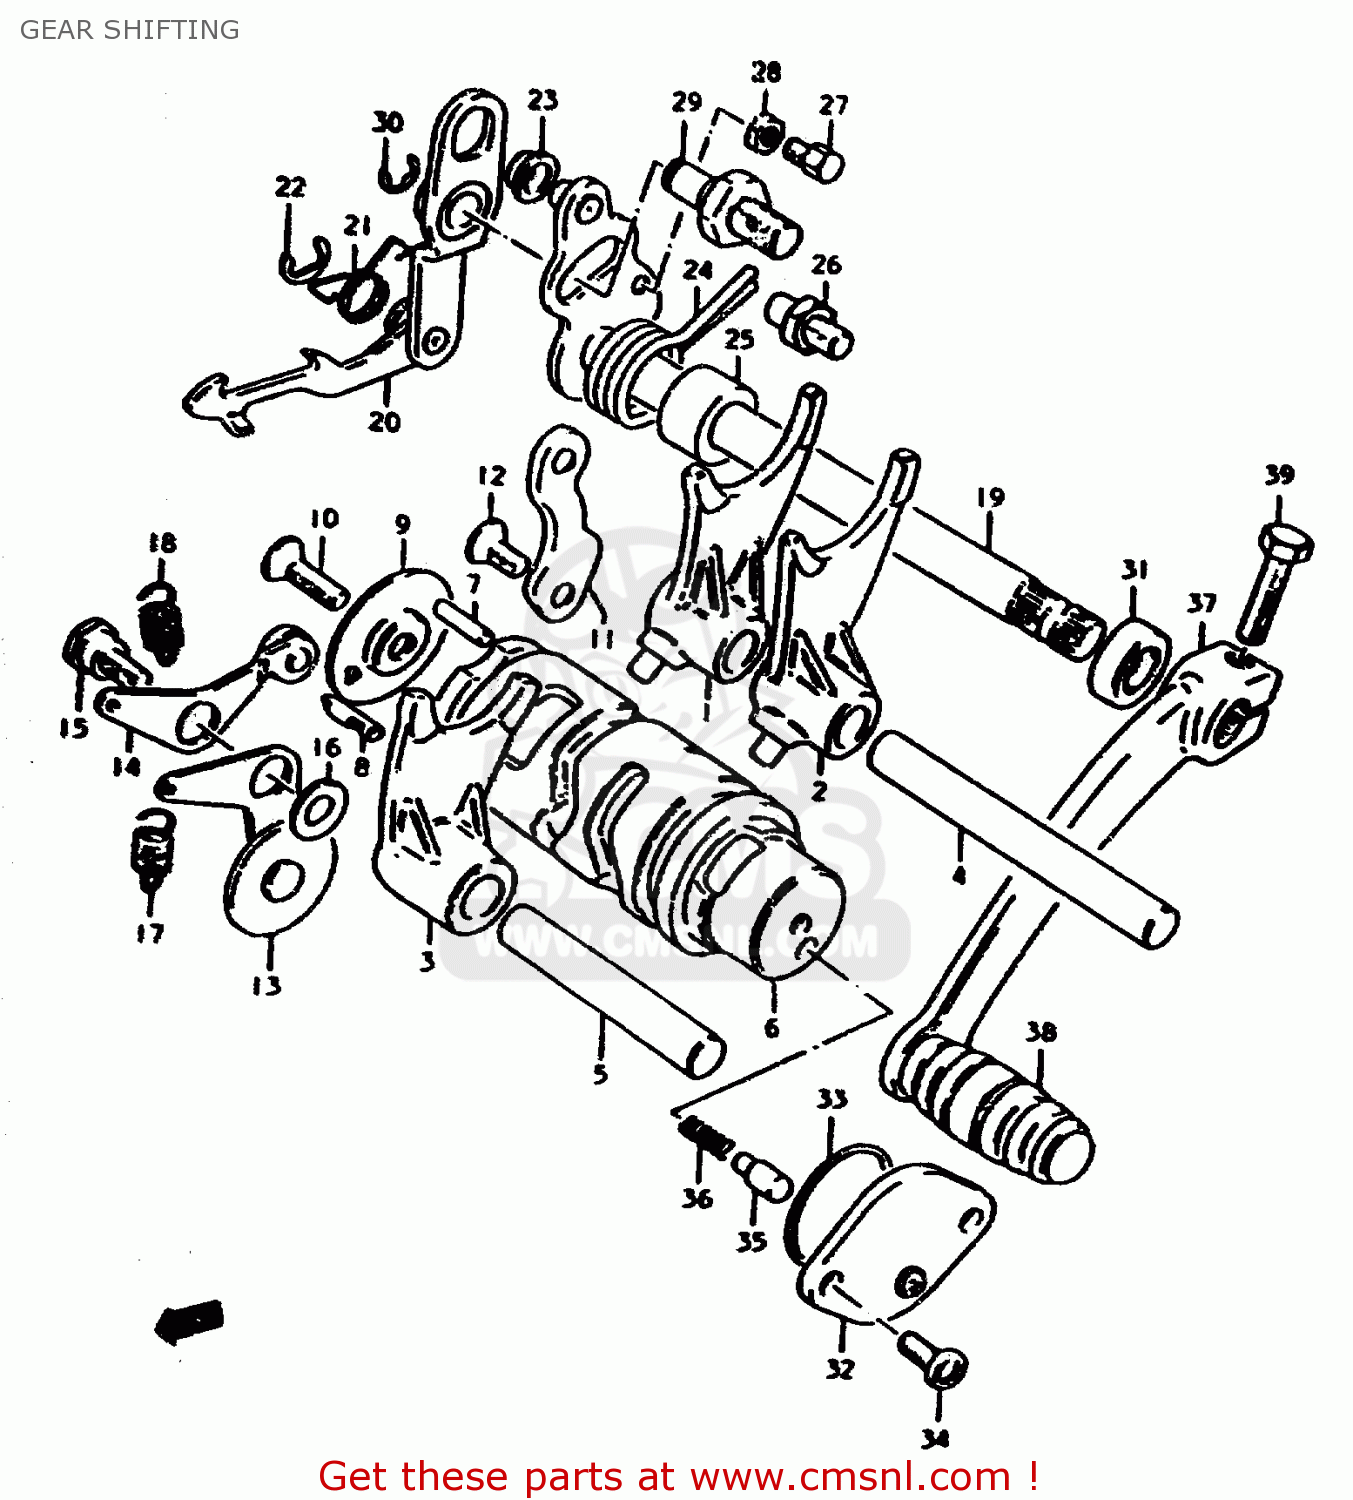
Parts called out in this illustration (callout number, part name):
1	FORK,GEAR SHIFT NO.1
2	FORK,GEAR SHIFT NO.2
3	FORK,GEAR SHIFT NO.2
4	SHAFT,GEAR SHIFT FORK
5	SHAFT,GEAR SHIFT FORK
6	CAM,GEAR SHIFT
7	PIN(4X15.8)
8	PIN
9	RETAINER,GEAR SHIFT CAM DR PIN
10	SCREW
11	GUIDE,GEAR SHIFT CAM
12	SCREW
13	STOPPER,GEAR SHIFT CAM
14	STOPPER,GEAR SHIFT CAM NEUTRAL
15	BOLT(6X18.3)
16	WASHER
17	SPRING
18	SPRING
19	SHAFT,GEAR SHIFT
20	PAWL,GEAR SHIFT
21	SPRING
22	E RING
23	SPACER(7X10X5)
24	SPRING
25	SPACER(12X20X15.3)
26	STOPPER,GEAR SHIFT CAM
27	BOLT,GEAR SHAFT RETURN SPR SET
28	NUT 6MM
29	STOPPER,GEAR SHIFT CAM
30	E RING 6MM
31	OIL SEAL
32	BODY,GEAR SHIFT SWITCH
33	O-RING (D:2.4 ID:26.2)
34	SCREW
35	PIN(5X15.5)
36	SPRING
37	LEVER, GEAR SHIFTING
38	RUBBER,GEAR SHIFT PEDAL
39	BOLT
